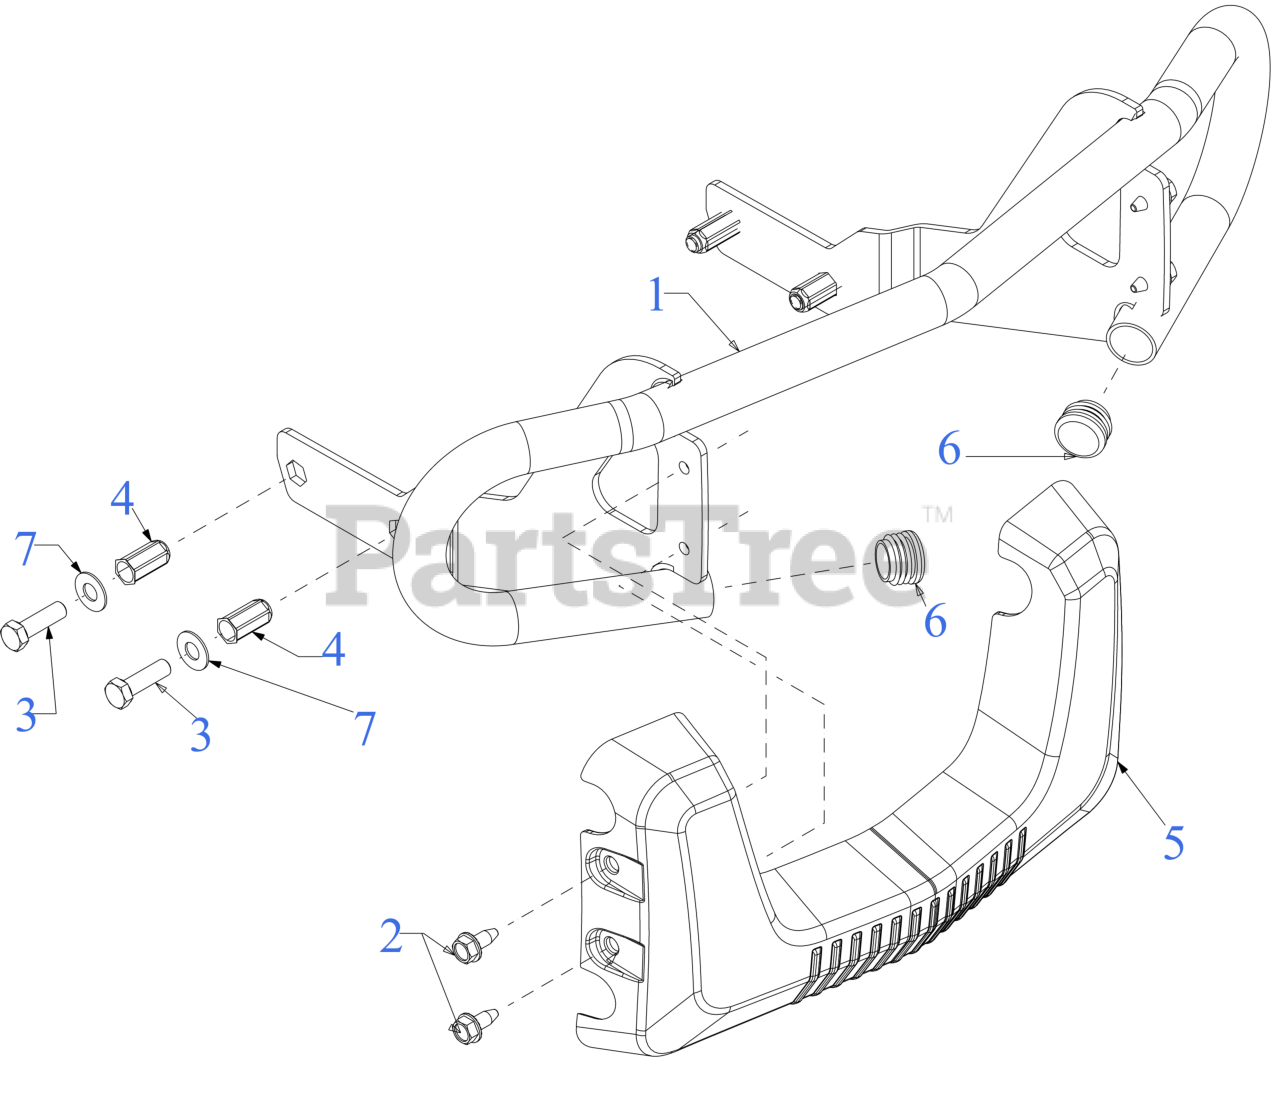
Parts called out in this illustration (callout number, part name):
1	BUMPER ASSEMBLY
2	SCREW M8-1.25 x .750
3	SCREW 3/8-16 x 1.25 GR5
4	NUT RIVET 3/8-16
5	BUMPER COVER
6	BUMPER TUBE CAP
7	FLAT WASHER .401X.88
